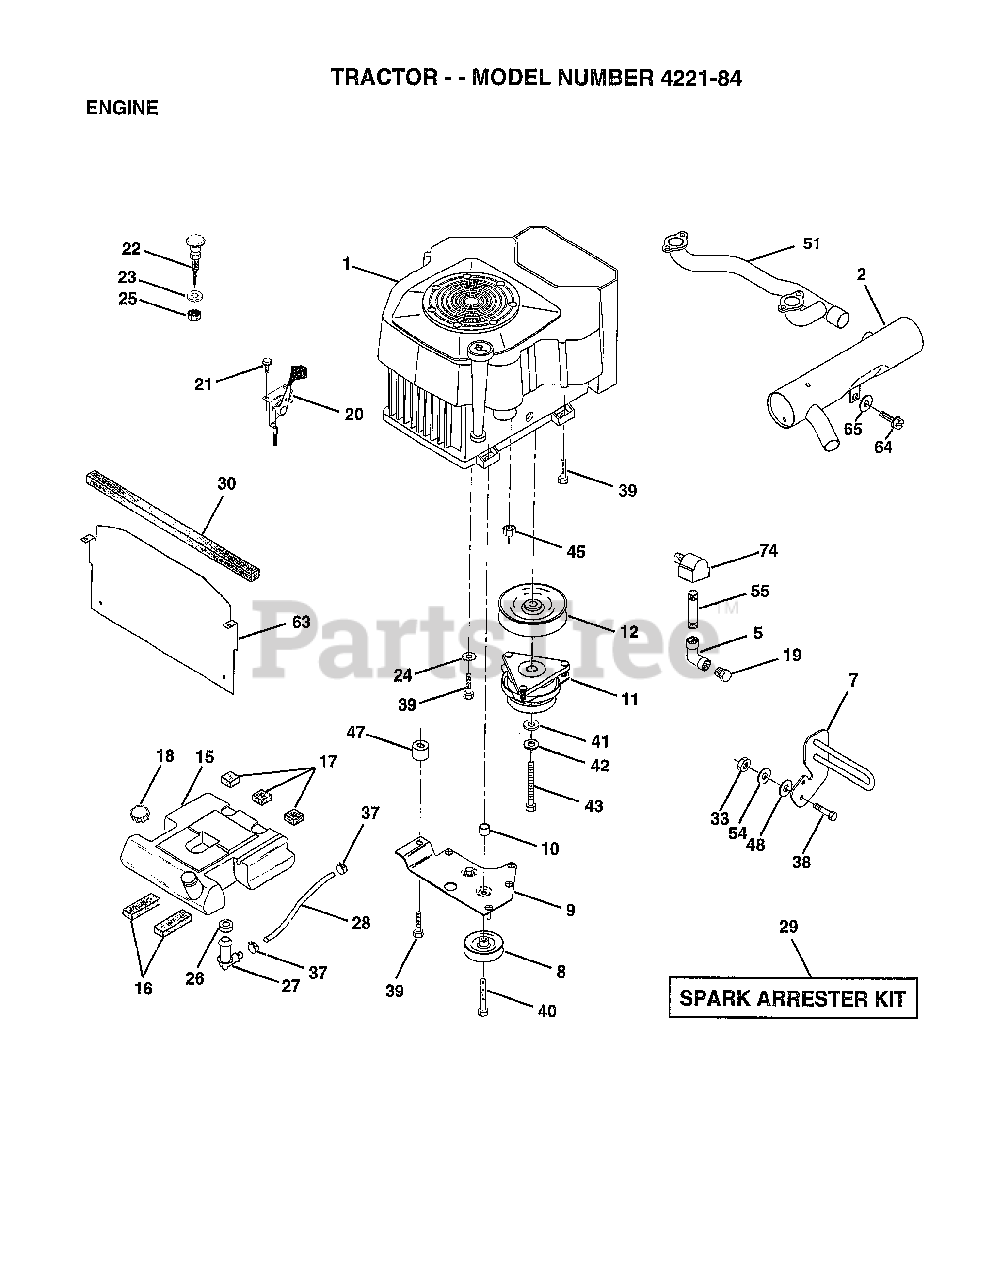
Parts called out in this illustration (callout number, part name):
2	MUFFLER SIDE1-1/8
5	ELBOW
7	GUARD.MUFFLER.ASM
9	KEEPER ASM BELT
10	BUSHING.
12	PULLEY.ENG.CLUTCH
15	TANK FUEL REAR
16	PAD IDLER TI
17	PAD-SPACER LT
18	CAP ASM FUEL
19	PLUG T
21	SCREW LT
22	CHOKE CONTROL
23	WASHER
24	LOCKWASHER
25	"NUT,KEPS 3/8-24IM"
26	BUSHING OUTLET T
27	STEM.TANK.FUEL
29	SPARK ARREST KIT
30	FOAM-STRIP LT
33	NUT
37	HOSE CLAMP
38	"BOLT,HEX"
39	SCREW.3/8-16X2.25
40	SCREW.TT.3/8-16X4
41	WASHER
42	LOCKWASHER
43	BOLT.7/16-20X4.25
45	NUT
47	SPACER.ENGINE
48	WASHER T
51	MANIFOLD PIPE VGT
54	WASHER
55	PIPE NIPPLE LT
63	HEAT.SHIELD.VGT.
64	SCREW
65	WASHER
74	ELBOW STREET BASS
